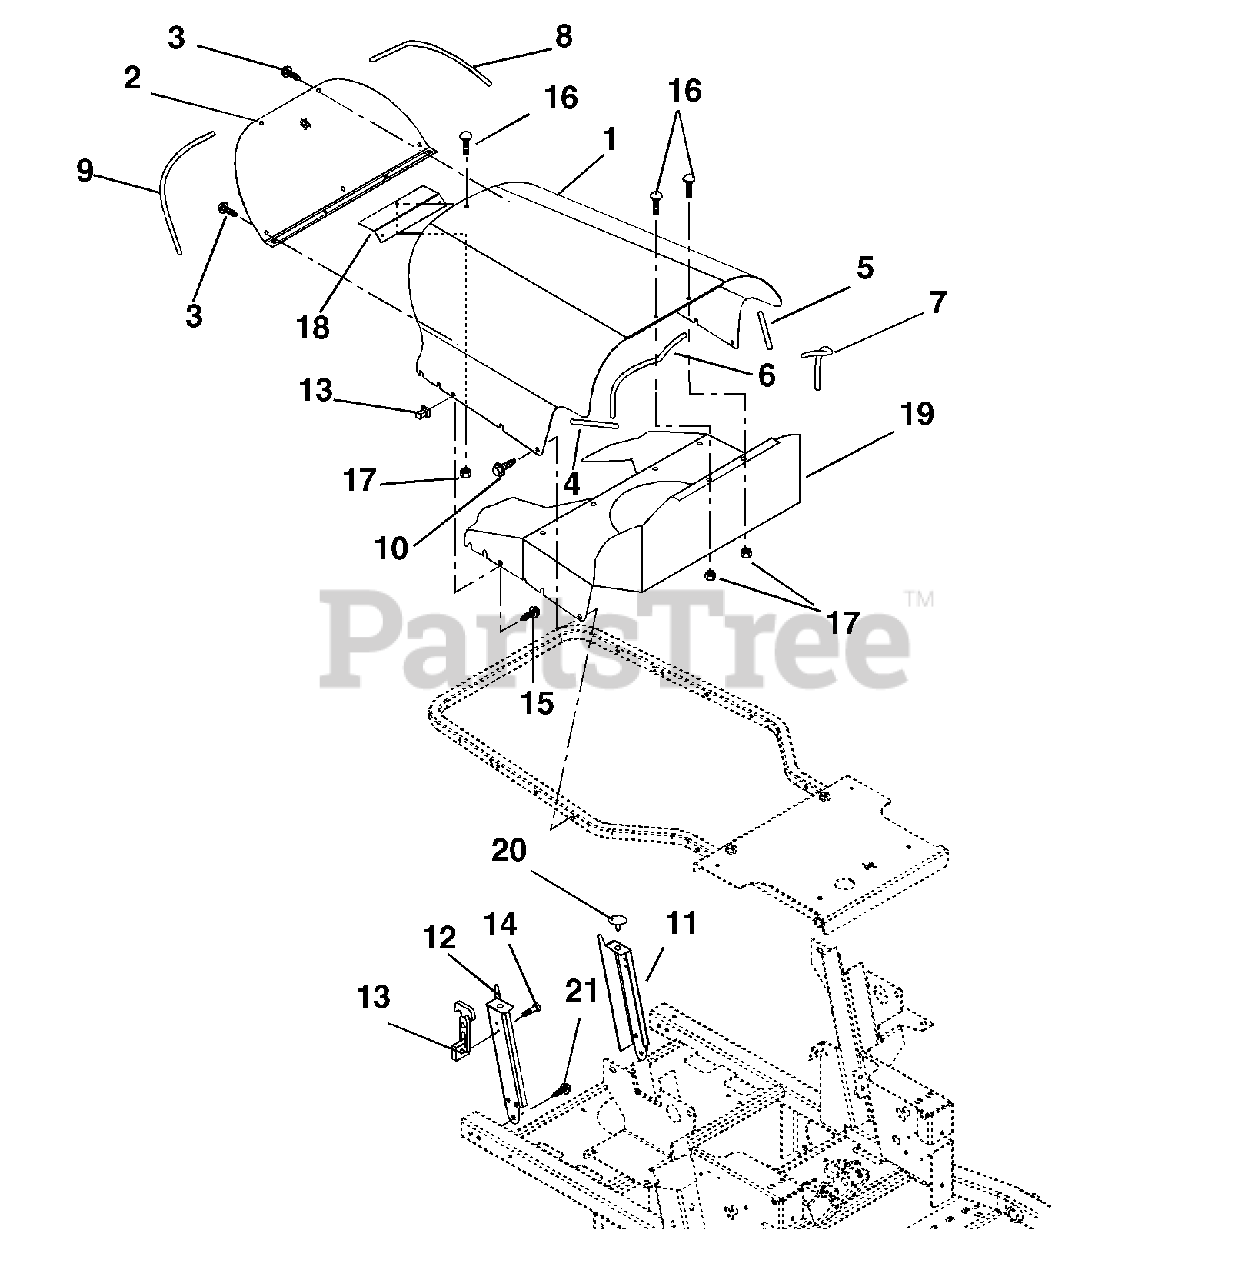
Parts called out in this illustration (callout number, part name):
2	Screen-Hood
3	Screw-Tapping .25-20 x .50 Hex Washer Head
4	Seal-Trim-Lok Bulk .06 Bubble
5	Seal-Trim-Lok Bulk .06 Bubble
6	Seal-Trim-Lok Bulk .06 Bubble
7	Seal-Trim-Lok Bulk .06 Bubble
8	Seal-Trim-Lok Bulk .06 Bubble
9	Seal-Trim-Lok Bulk .06 Bubble
10	Screw-Tapping .38-16 x .50 Hex Washer Head
11	Hood Support Left-Hand
12	Hood Support Right-Hand
13	Latch-Rubber
14	Screw-Machine 10-24 x .50 Hex Washer Head
15	Screw Machine 10-24 x .50 Hex Washer Head
16	Bolt-Round Head Square Shank .25-20 x .50 Grade 5
17	Nut-Locking-Nylon .25-20
18	Bracket-Screen Support
19	Weldment, Plenum
20	Button Bumper
21	Screw-Tapping .38-16 x .75 Hex Washer Head
